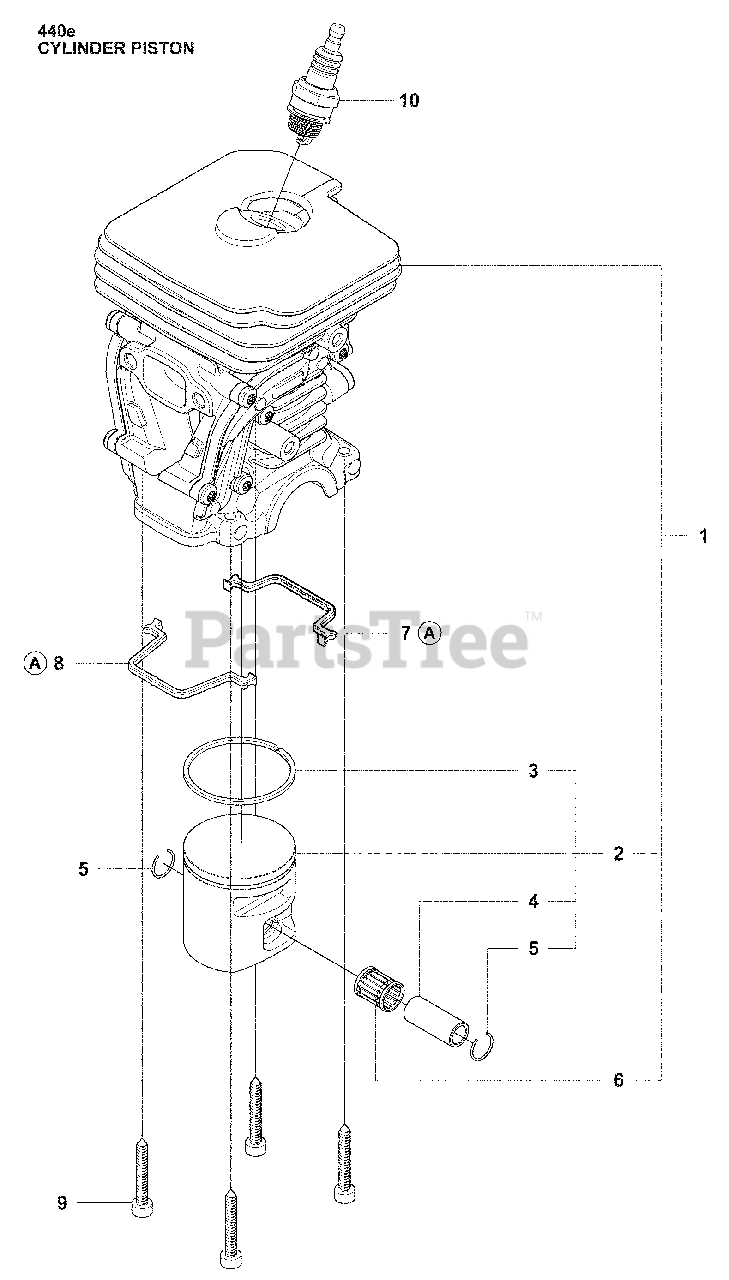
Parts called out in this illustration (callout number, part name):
1	Cylinder Assembly
2	Piston Assembly
3	Piston Ring
4	Piston Pin
5	Locking Ring
6	Support Bushing
7	Cylinder Gasket, Rear
8	Cylinder Gasket, Front
9	Screw, MC6S 5 X 25
10	Solid Spark Plug, BPMR7A
